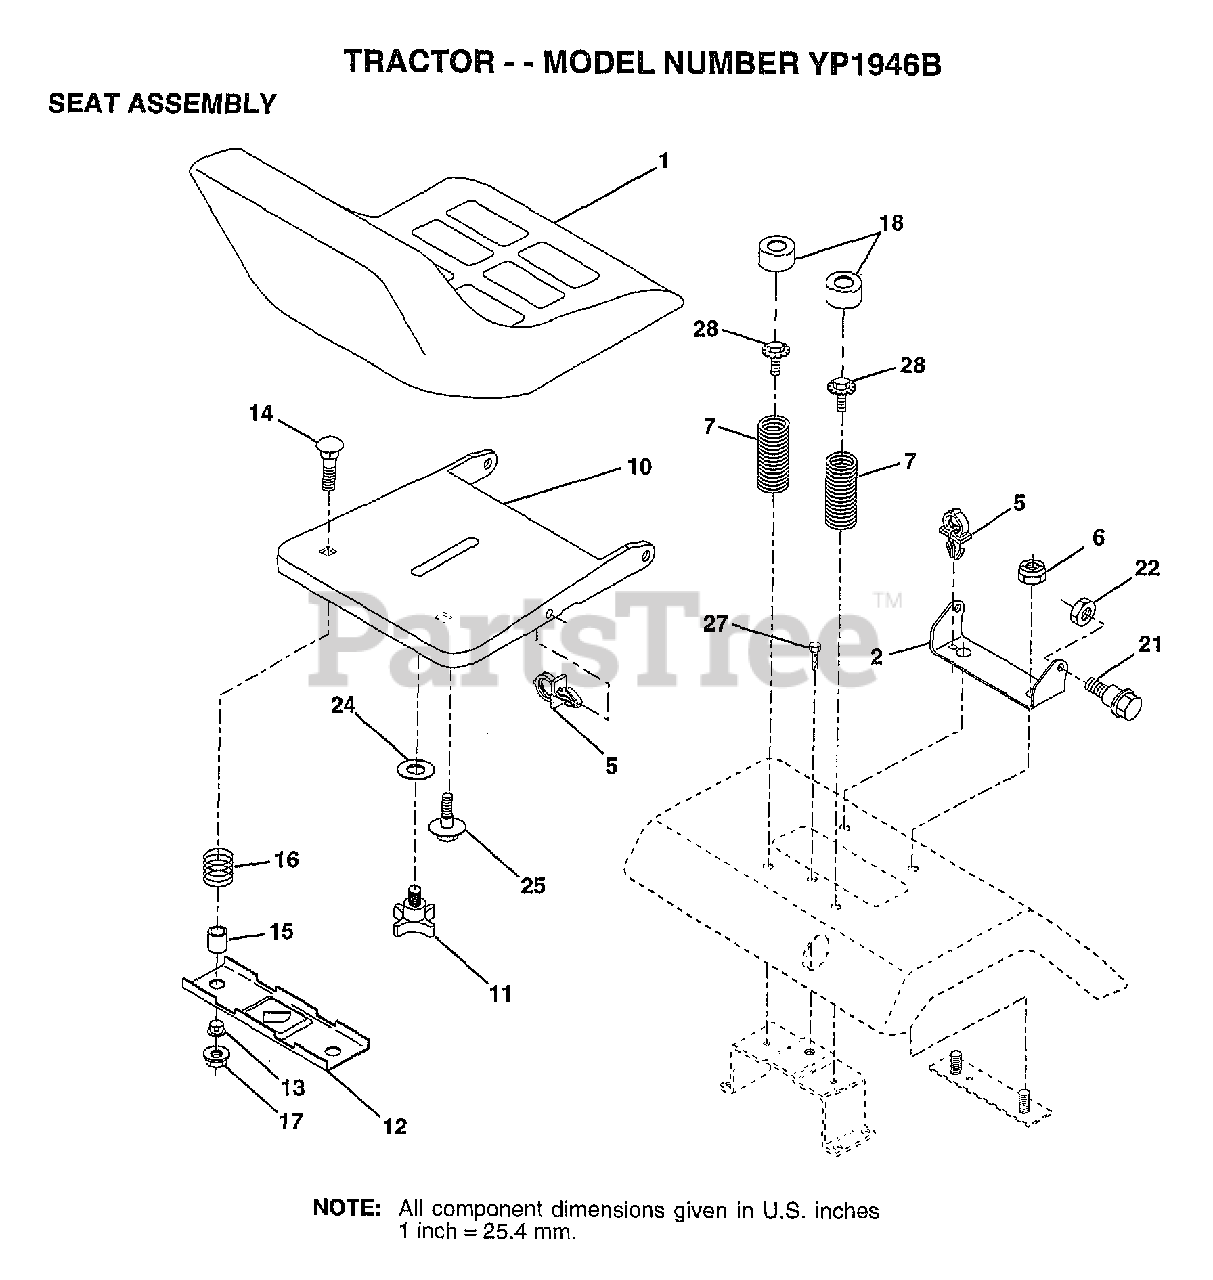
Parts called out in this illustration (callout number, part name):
1	SEAT.2500/1516.BK
2	BRACKET PVT SEAT
5	CLIP.PUSH-IN.HING
6	NUT
7	SPRING COMPRESSIO
10	PAN-SEAT
11	"KNOB 1/2"" YT"
12	BRKT SWITCH
13	BUSHING
14	BOLT-RD HD SQ NK
15	SPACER SPLIT
16	SPRING COMPRESSED
18	CAP SPRING
21	"BOLT,SHOULDER"
22	NUT
24	WASHER
25	"BOLT,SHOULDER"
27	SCREW LT
28	BOLT.5/16-18.UNC
